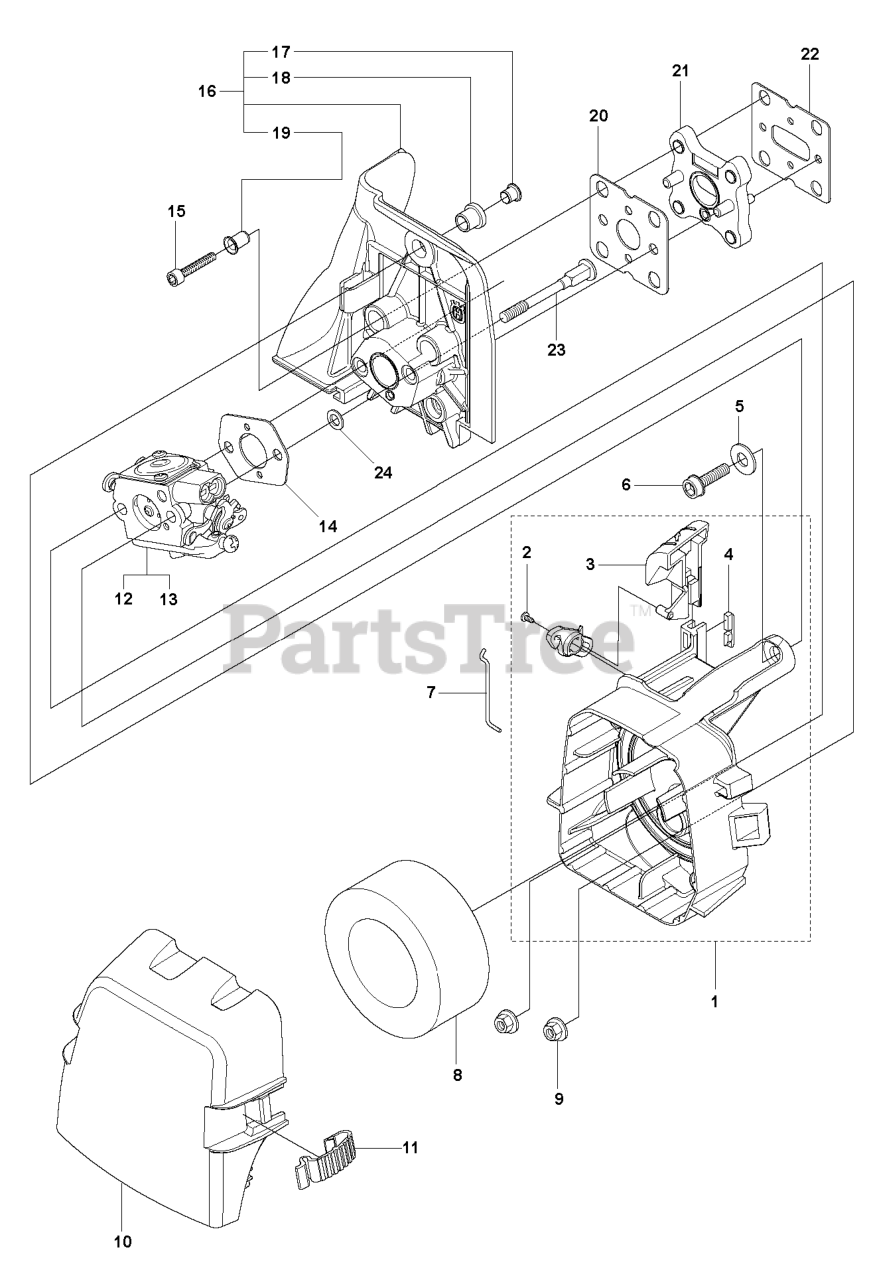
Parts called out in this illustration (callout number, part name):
1	FILTER HOLDER ASSY
3	CHOKE CONTROL
6	SCREW IHSCFM
10	FILTER COVER
12	CARBURETTOR C1Q-EL38
13	CARBURETTOR C1Q-EL39A
15	SCREW
16	INSULATION WALL ASSEMBLY
20	GASKET INTAKE
22	GASKET INTAKE
24	WASHER
